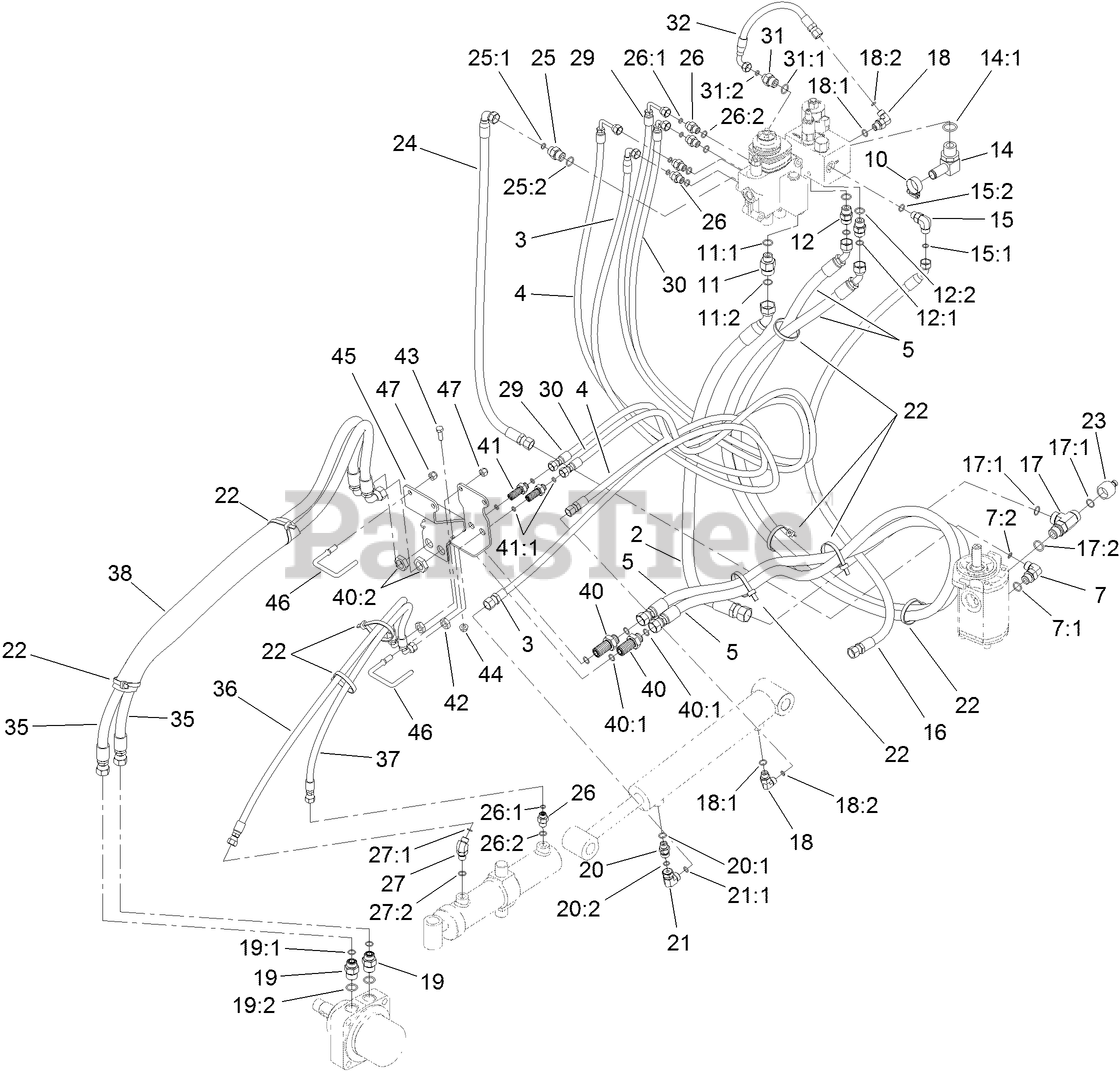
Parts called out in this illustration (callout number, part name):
2	HOSE-HYD
3	HOSE-HYD
4	HOSE-HYD
5	HOSE-HYD
7	FITTING-HYD, 90 DEG
7:1	O-RING
7:2	O-RING
10	CLAMP-HOSE
11	FITTING-STR
11:1	O-RING
11:2	O-RING
12	FITTING-STRAIGHT
12:1	O-RING
12:2	O-RING
14	FITTING-ELB 90
14:1	O-RING
15	FITTING-ELBOW, 90 DEG
15:1	O-RING
15:2	O-RING
16	HOSE-HYD
17	FITTING-TEE
17:1	O-RING
17:2	O-RING
18	FITTING-ELBOW 90
18:1	O-RING
18:2	O-RING
19	FITTING-STRAIGHT
19:1	O-RING
19:2	O-RING
20	VALVE-CHECK
20:1	O-RING
20:2	O-RING
21	FITTING-HYD, 90 DEG
21:1	O-RING
22	TIE-CABLE
23	NIPPLE
24	HOSE-HYD
25	FITTING-STRAIGHT
25:1	O-RING
25:2	O-RING
26	FITTING-STRAIGHT
26:1	O-RING
26:2	O-RING
27	FITTING
27:1	O-RING
27:2	O-RING
29	HOSE-HYD
30	HOSE-HYD
31	FITTING-STR
31:1	O-RING
31:2	O-RING
32	HOSE-HYD
35	HOSE ASM-HYD HP
36	HOSE-HYD
37	HOSE-HYD
38	SLEEVE-PROTECTIVE
40	FITTING-BULKHEAD
40:1	O-RING
40:2	NUT-BULKHEAD
41	UNION-BULKHEAD
41:1	O-RING
42	NUT-LOCK
43	SCREW-HH
44	NUT-HF
45	BRACKET-BULKHEAD
46	GUIDE-HOSE
47	NUT-LOCK, NI
